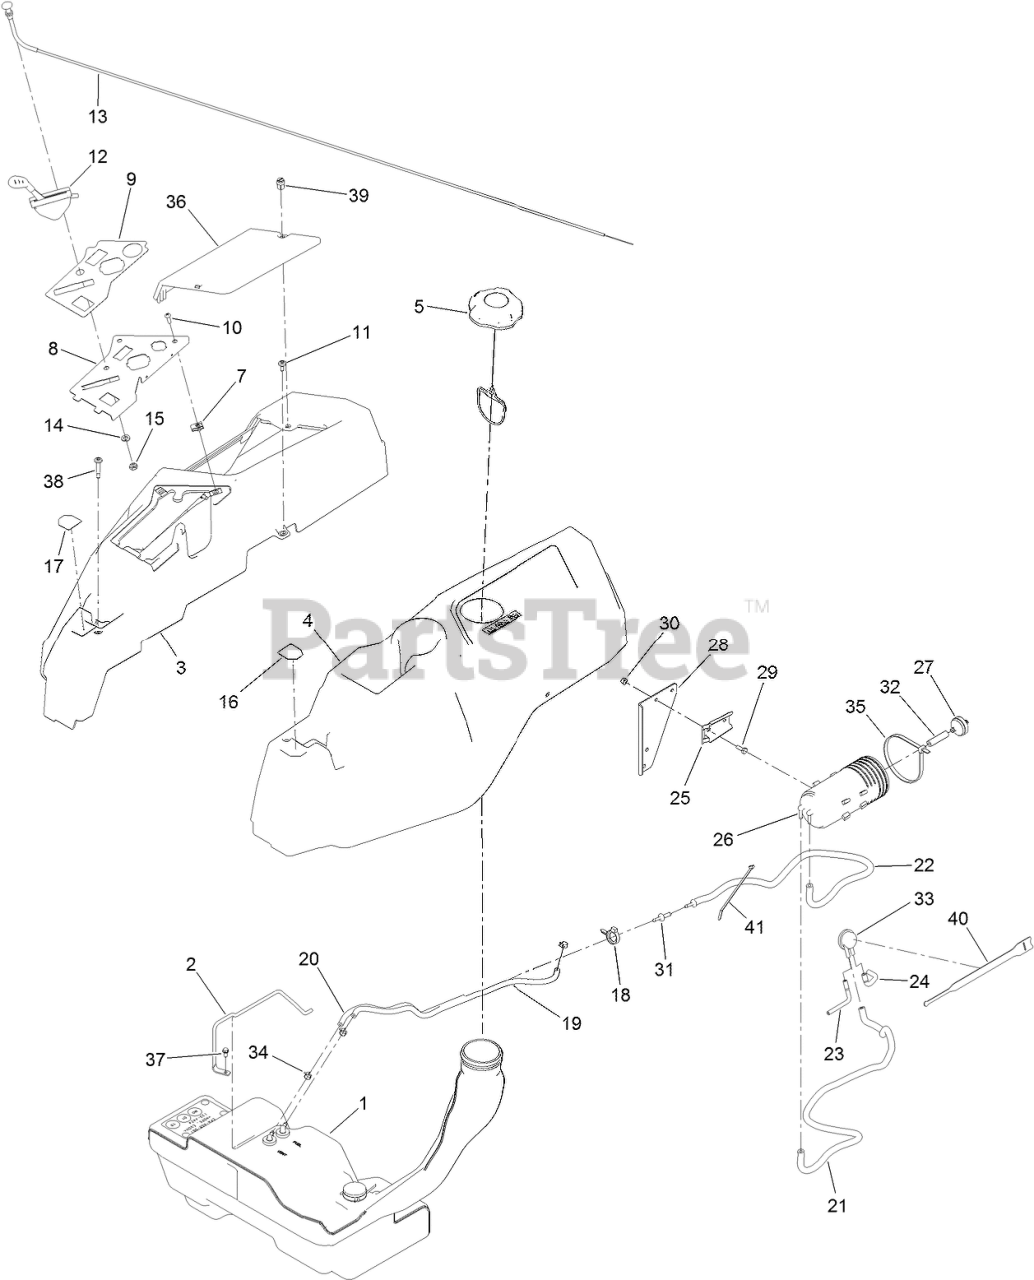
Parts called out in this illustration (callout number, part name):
1	FUEL TANK ASM
2	ROD-HOLD DOWN
3	POD-RH
4	POD-LH
5	CAP-FUEL, RATCHETING
8	PANEL-CONTROL
9	DECAL-CONTROL W/CHOKE
10	SCREW-PRH
11	SCREW-SHOULDER
12	CABLE-THROTTLE
13	CABLE-CHOKE
14	WASHER-LOCK
15	NUT-HJ
16	DECAL-LEVER, CONTROL (LH)
17	DECAL-LEVER, CONTROL (RH)
18	CLAMP-HOSE
19	HOSE-FUEL
20	HOSE-FUEL
21	HOSE-FUEL
22	HOSE, FUEL
23	HOSE-VENT, FORMED
24	HOSE-VENT, FORMED
25	BRACKET-CANISTER, CARBON
26	CANISTER-CARBON, 800CC
27	FILTER-FUEL, INLINE
28	CARB CANISTER BRACKET
29	SCREW-HH
30	NUT-LOCK, NI
31	ADAPTOR-ORIFICE
32	HOSE-FUEL
33	VALVE-CONTROL, VACUUM
34	CLAMP-HOSE
35	TIE-CABLE
36	COVER-BATTERY
37	SCREW-HWH
38	SCREW-SHOULDER
39	FASTENER
40	STRAP-VELCRO, CABLE TIE
41	TIE-CABLE
